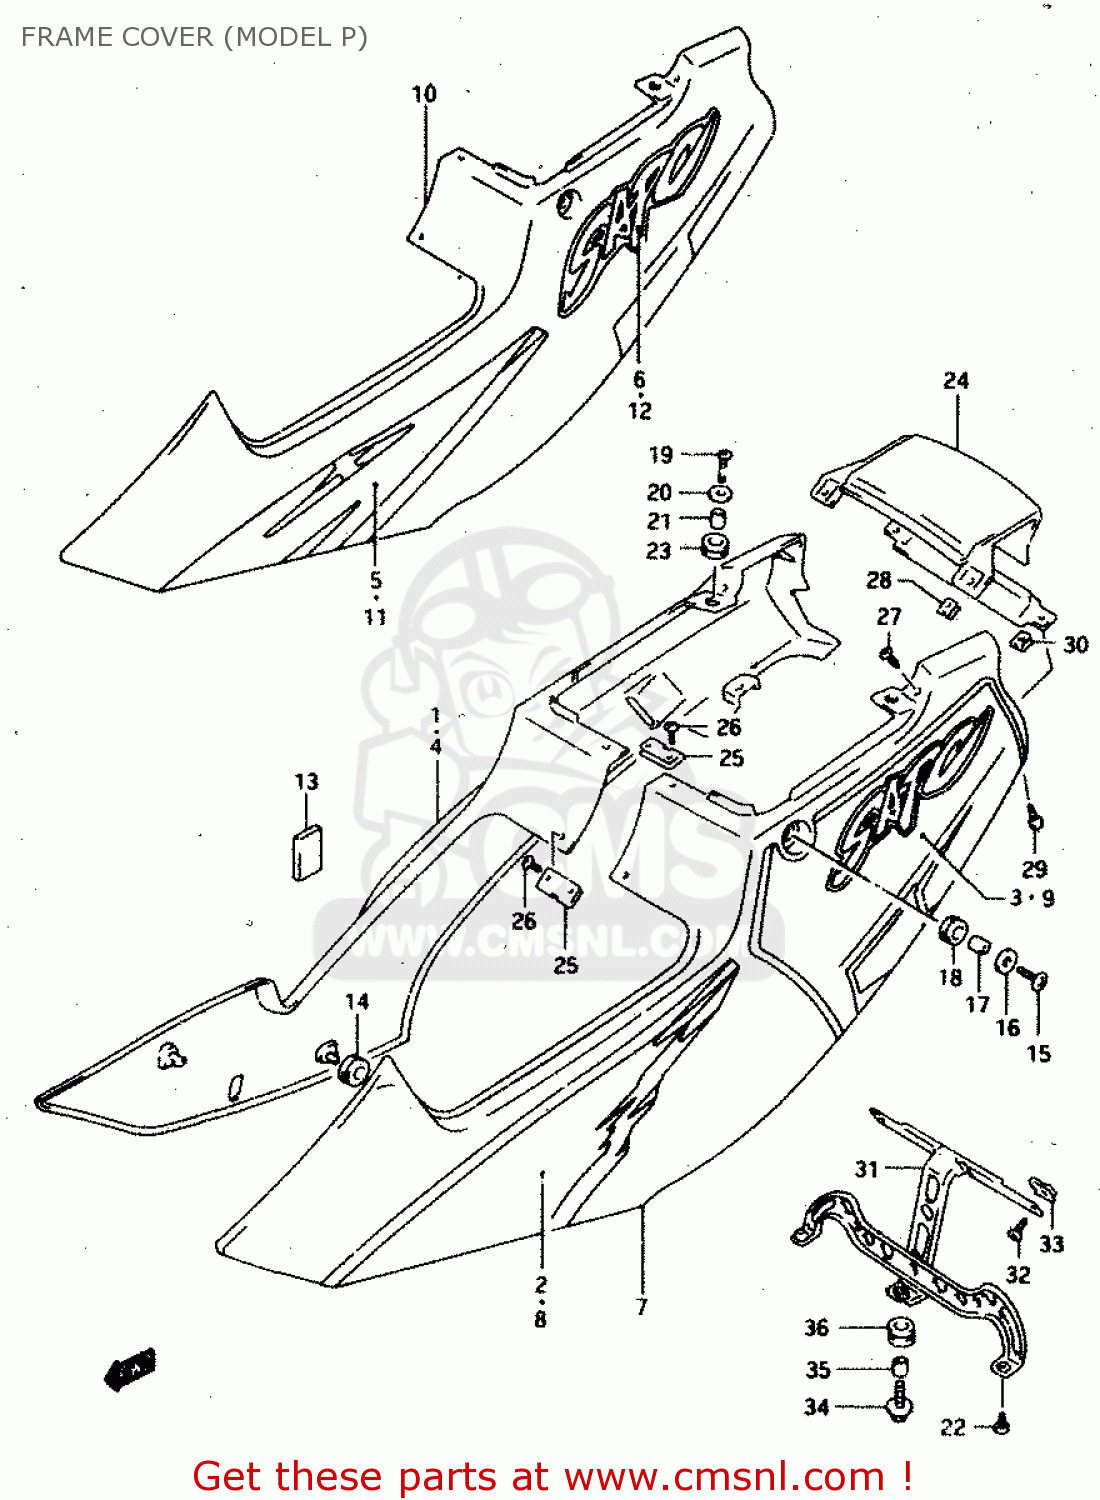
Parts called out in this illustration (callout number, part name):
1	COVER,FRAME,R
2	TAPE,FRAME COVER STRIPE,R
3	TAPE, ZEKKEN
4	COVER,FRAME R.
5	TAPE,FRAME COVER,R
6	EMBLEM,FRAME COVER
7	COVER,FRAME,L.
8	TAPE,FRAME COVER STRIPE,L
9	TAPE, STICKER
10	COVER, FRAME LH (BLACK)
11	TAPE,FRAME COVER,L
12	EMBLEM,FRAME COVER
13	TAPE,FRAME PROTECTOR
14	CUSHION
15	SCREW
16	WASHER(6.5X22X1.6)
17	SPACER (6.3X9.1X6.7)
18	CUSHION
19	SCREW
20	WASHER (6.5X20X1.6)
21	SPACER (6.3X9.1X6.7)
22	SCREW (6X16)
23	CUSHION
24	COVER,FRAME CN
25	NUT,FRAME COVER CTR
26	SCREW
27	SCREW, BRACKET
28	NUT
29	SCREW
30	NUT
31	BRKT,TAILLAMP,
32	SCREW
33	NUT
34	BOLT(6X20)
35	SPACER (6.1X8X9.5)
36	CUSHION
